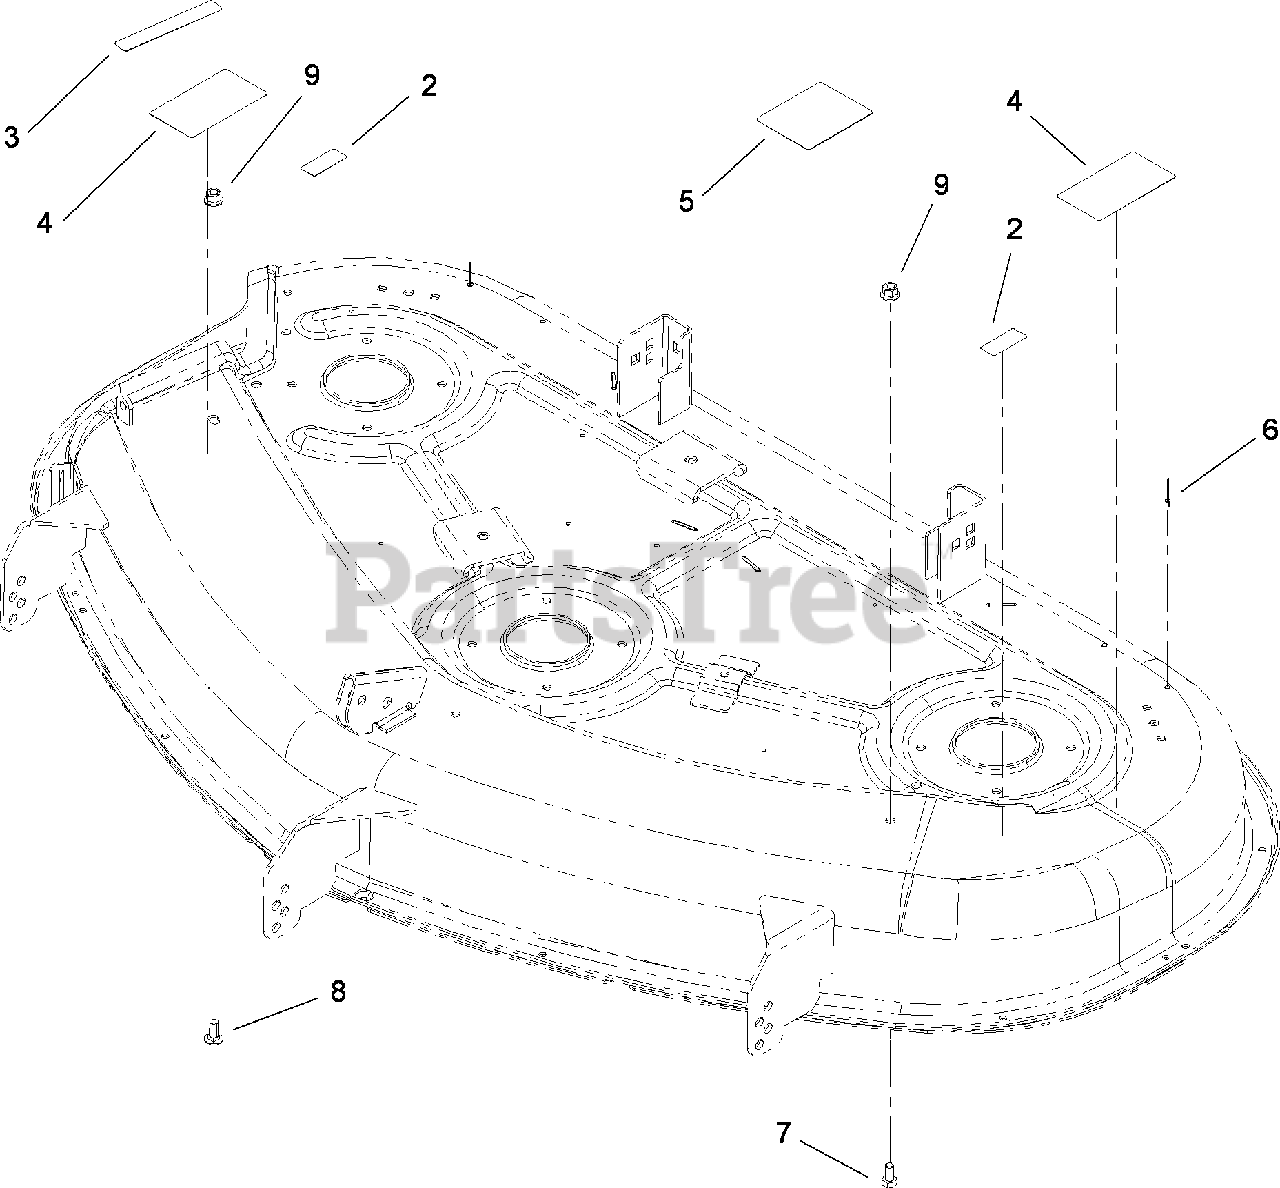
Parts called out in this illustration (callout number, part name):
2	DECAL-DANGER, PULLEY
3	DECAL-DANGER, DEFLECTOR
4	DECAL-DANGER
5	DECAL-ROUTING, BELT
6	RIVET-BLIND
7	SCREW-HH
8	SCREW-CARR
9	NUT-LOCK, NI
